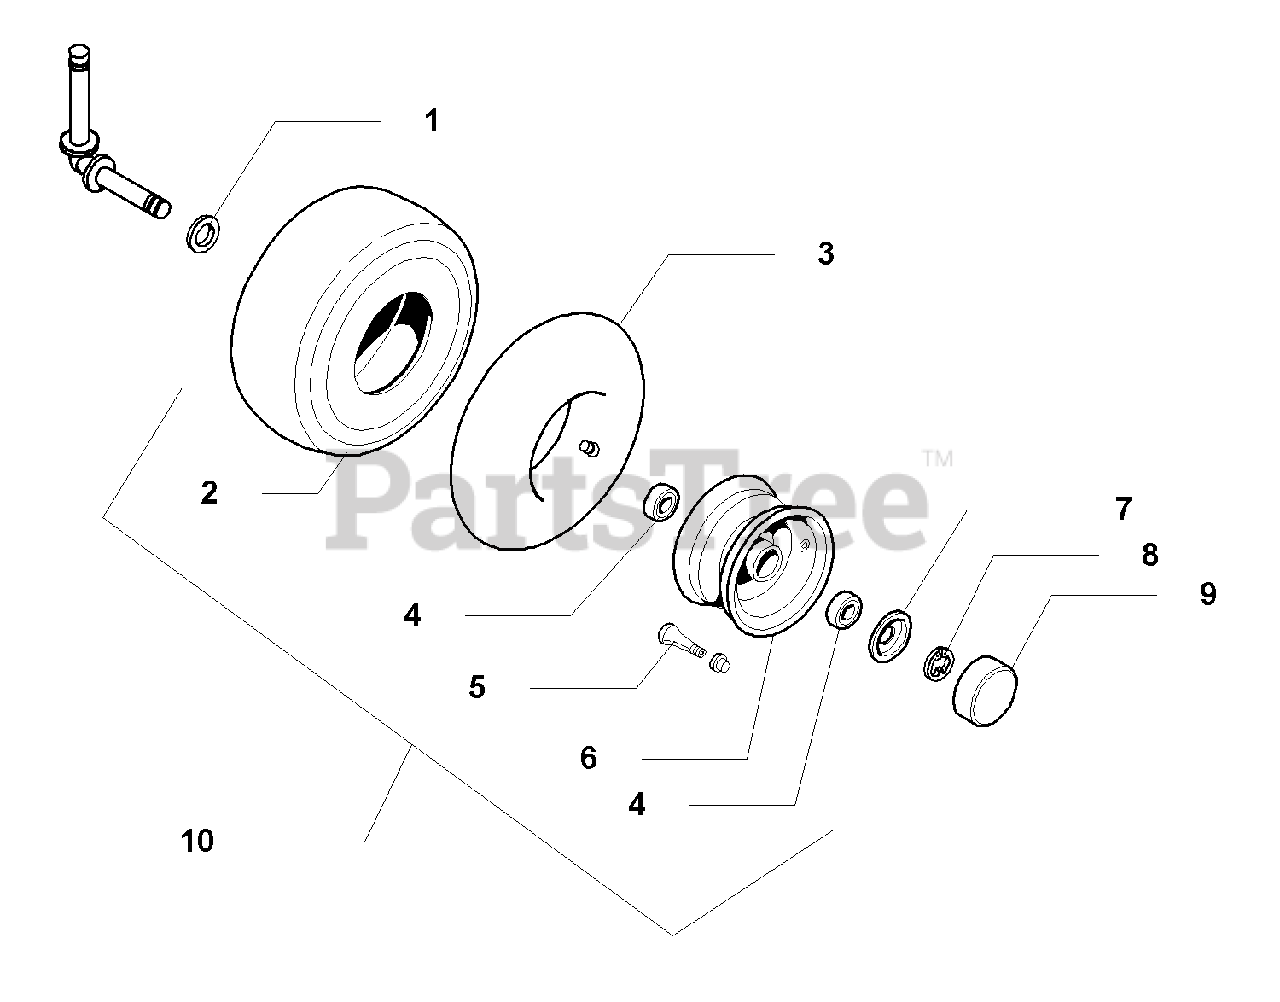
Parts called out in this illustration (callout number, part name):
1	WASHER, Special 3/4 (Install to the inside of wheel)
2	TIRE, 15 x 6.00-6 (Dico)
3	TUBE, 4.10/3.50-6
4	BALL BEARING
5	VALVE STEM & CAP
6	WHEEL ASSEMBLY, Metallic Gray (Includes Ref. No. 4)
7	RETAINER, Cap, Hub
8	RING, Retaining
10	WHEEL & TIRE ASSEMBLY 15 x 6.00-6, Metallic Gray (Includes Ref. Nos. 2, 4, 5, & 6)
